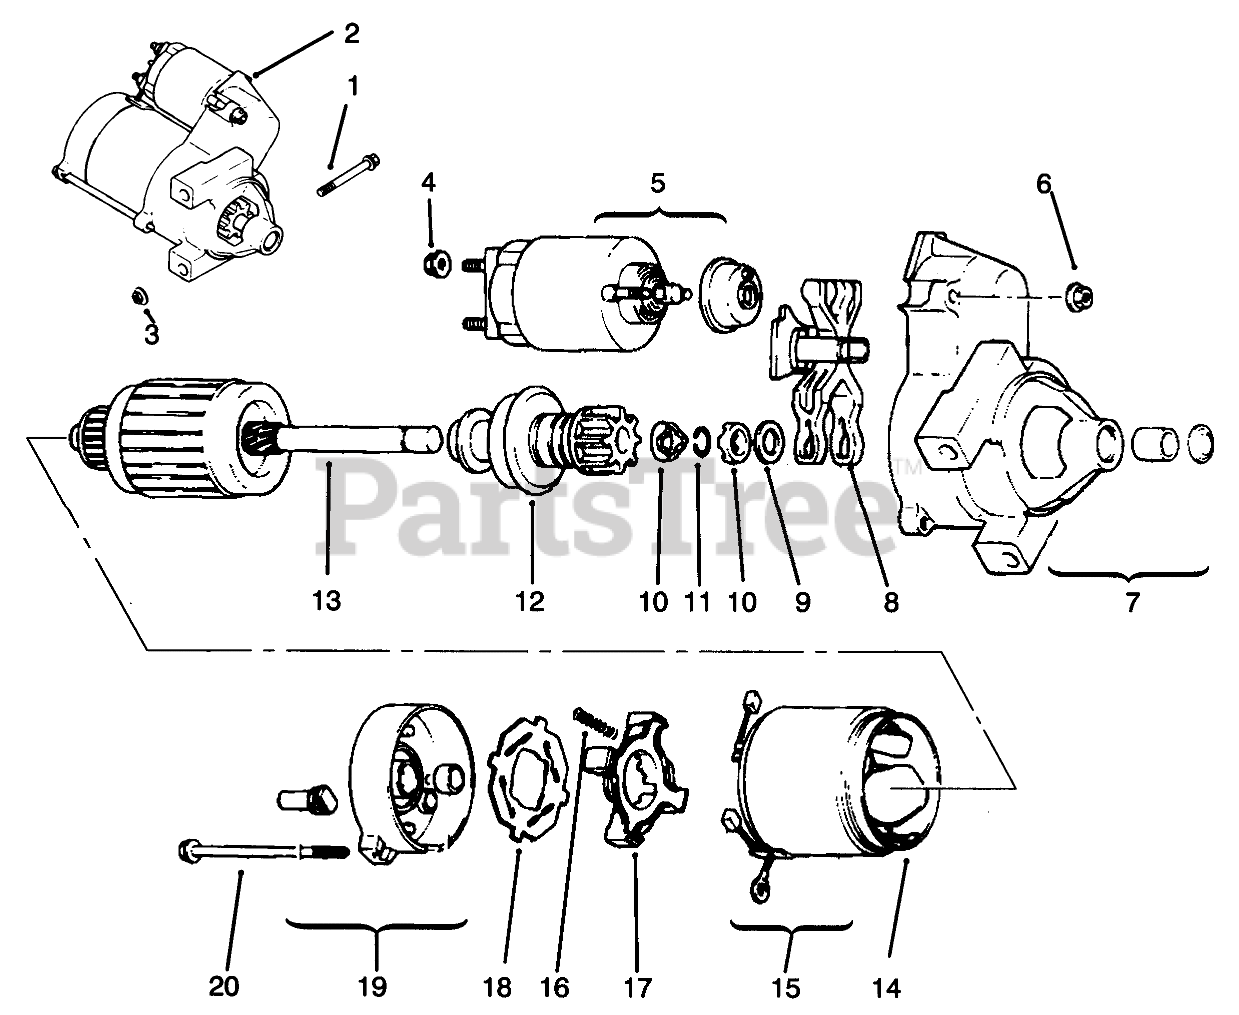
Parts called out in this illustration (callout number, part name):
1	Screw M8x1.25x80 (Only On: 72103)
2	Starter INCL 4-20 (Only On: 72103)
3	Nut M8x1.25 (Only On: 72103)
4	Nut-Starter (Only On: 72103)
5	Solenoid (Only On: 72103)
6	Nut Starter (Only On: 72103)
7	Cap-Drive End (Only On: 72103)
8	Lever Starter Drive (Only On: 72103)
9	Washer-Thrust (Only On: 72103)
10	Nut-Stop Collar (Only On: 72103)
11	Ring-Retainer (Only On: 72103)
12	Drive-Pinion (Only On: 72103)
13	Armature-Starter (Only On: 72103)
14	Frame (Only On: 72103)
15	Kit-Brush INCL 16 (Only On: 72103)
16	Spring-Brush (Only On: 72103)
17	Holder-Brush (Only On: 72103)
18	Insulator (Only On: 72103)
19	Cap-Commutator End (Only On: 72103)
20	Bolt (Only On: 72103)
